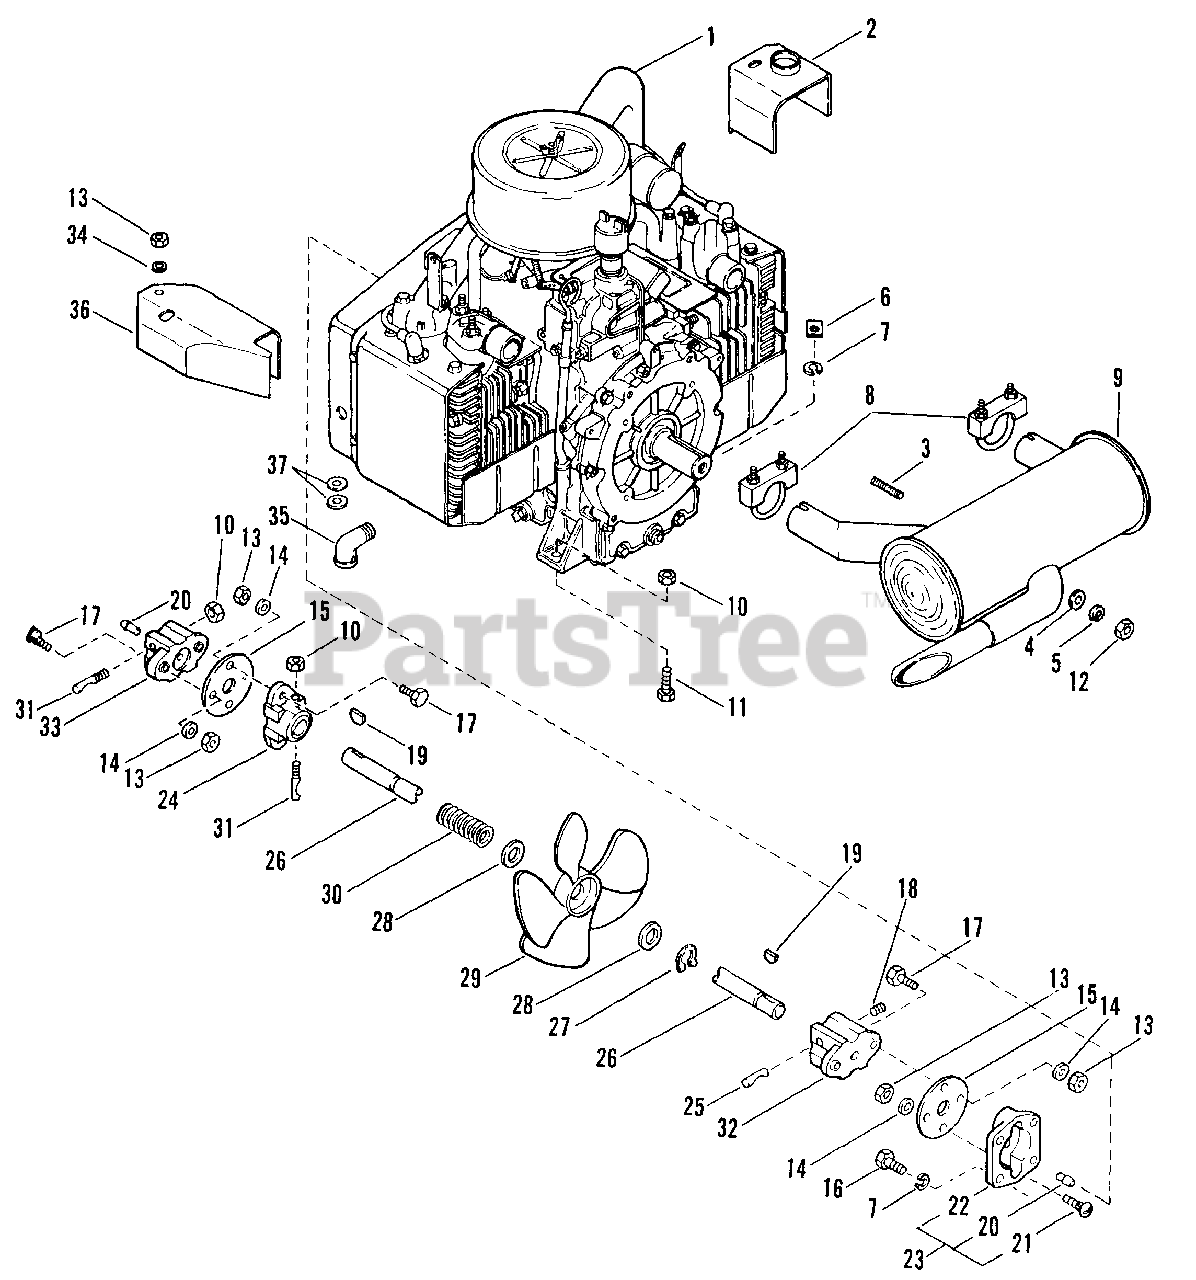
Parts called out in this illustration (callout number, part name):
1	Engine, 18 HP Kohler
2	Left Exhaust Shield
3	Engine Stud
4	Washer, Flat .250 x .500 x .049
5	Washer, Lock 1/4 Reg.
6	Nut, Special 3/8-16
7	Washer, Lock 3/8 Reg.
8	Exhaust Clamp, 1.50
9	Muffler, Twin Exhaust
10	Nut, Lock 3/8-16
11	Bolt, Hex 3/8-16 x 1.25
12	Nut, Hex 1/4-20
13	Nut, Lock 5/16-18
14	Washer, Flat .375 x .734 x .065
15	Spacer Coupling
16	Bolt, Hex 3/8-16 x .875
17	Bolt, Hex 5/16-18 x .875
18	Set Screw, 3/8-16 x 1/2 SKHCUP
19	Key, Woodruff .187 x .75 #9
20	Pin, Groove 5/16 x 3/4 Type D
21	Bolt, Rib Neck 5/16-18 x 7/8
22	Drive Hub, Flywheel Twin
23	Engine Coupling Assembly, Twin
24	Drive Shaft Hub
25	Lock Stud
26	Drive Shaft
27	Ring, Retaining .750 Shaft
28	Washer, .752/.762 x 1.250 x .031
29	Fan
30	Spring, Comp. 2-1/2 Free Length
31	Lock Stud
32	Drive Hub, Twin Shaft
33	Drive Hub, Hydro
34	Washer, Flat .312 x .734 x .065
35	Street Elbow
36	Right Exhaust Shield
37	Washer, Flat .406 x .812 x .065
